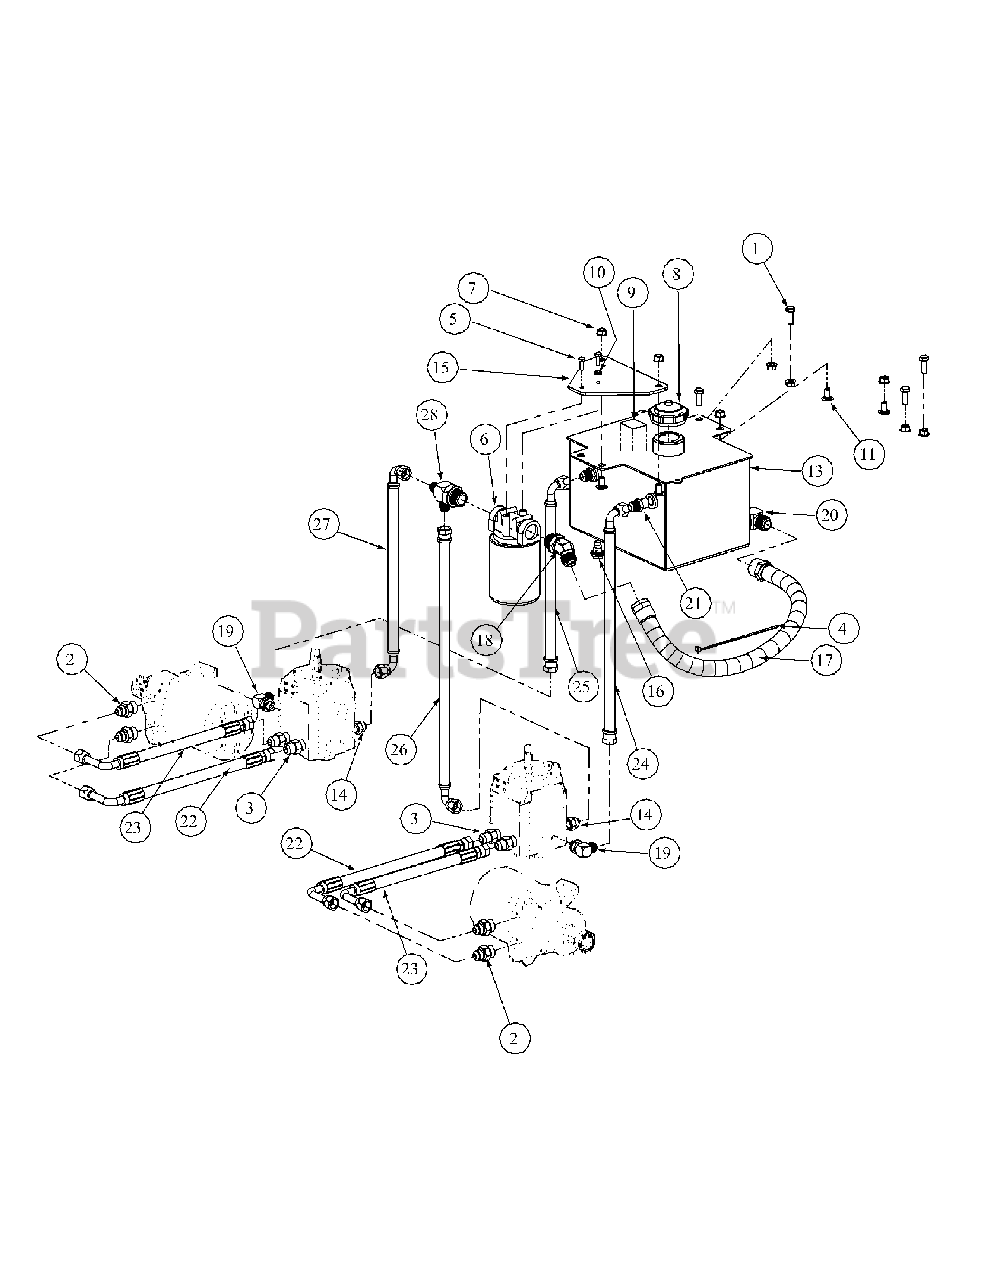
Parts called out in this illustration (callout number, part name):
1	Hex Cap Screw, 3/8-16, 1
2	Fitting 1/2 x 3/4 - O Ring
3	Fitting 1/2 x 3/4 - O Ring to Flare
4	Cable Tie, 3/16 x .05 x 7.4
5	Hex Cap Screw, 1/4-20, .75
6	Filter Head 3/4
7	Hex Nut Flange Lock, 3/8-16
8	Cap, Hydro Oil Tank
9	Decal Oil Only 20W50
10	Lock Washer, 1/4
11	Carriage Bolt, 3/8-16 x .75 LG.
13	Hydraulic Tank Assembly
14	Fitting Connector, 1/2 x 3/8
15	Oil Filter Mounting Plate
16	Oil Pan Drain w/ Seal and Plug
17	Tank to Filter Hose Assembly
18	Connector, 3/4 x3/4
19	Elbow Fitting, 3/8 O-ring, 1/2 Flare
20	Fitting Elbow, 1/2 x 1/2
21	Fitting, 3/8 NPT, 1/2 Flare
22	Long Pressure Hose Assembly
23	Short Pressure Hose Assembly
24	17.75" Return Hose Assembly, RH
25	14" Return Hose Assembly, LH
26	21.25" Supply Hose Assembly, RH
27	15.50" Supply Hose Assembly, LH
28	Tee Fitting, 3/4 x 1/2 x 1/2
